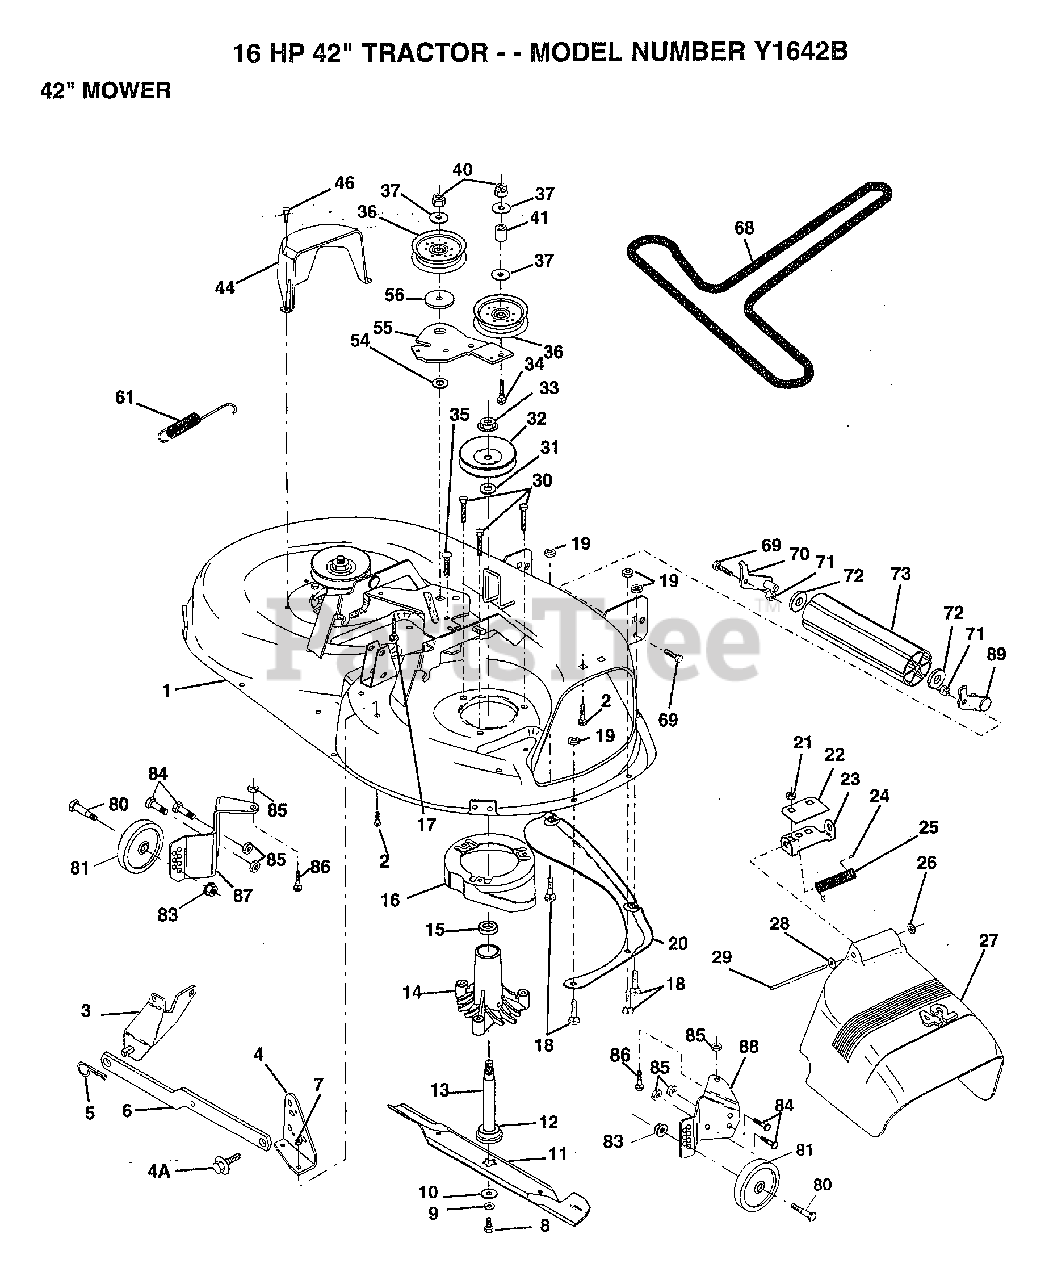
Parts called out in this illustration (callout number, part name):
2	BOLT
3	BRKT ASM SWAY BAR
4	BRKT DECK SW BAR
4A	BOLT SHD 5/16-18
7	NUT
8	BLADE BOLT
10	WASHER BLADE
11	"BLADE.42"" HIPERF"
12	BEARING.BALL
14	HSG ASM MANDREL
15	BEARING
17	BOLT
18	BOLT
19	NUT
22	STIFFENER BRKT
23	DEFLECTOR BRKT
24	CAP-SLEEVE LT
25	SPRING TORSION
26	NUT PUSH M
27	DEFLECTOR.SHIELD
28	WASHER
29	HINGE ROD
31	WASHER
34	BOLT
35	XMAS TREE FASTNER
36	FLAT IDLER PULLEY
37	WASHER
46	SCREW.1/4-20X5/8
54	HARDENED WASHER
55	IDLER ARM
56	SPACER RETAINER
61	SPRING.EXTENSION
68	BELT-V.92.4.MWR
69	BOLT
72	WASHER
80	BOLT M
81	WHEEL.GAGE.BLK.PL
83	NUT
84	BOLT
